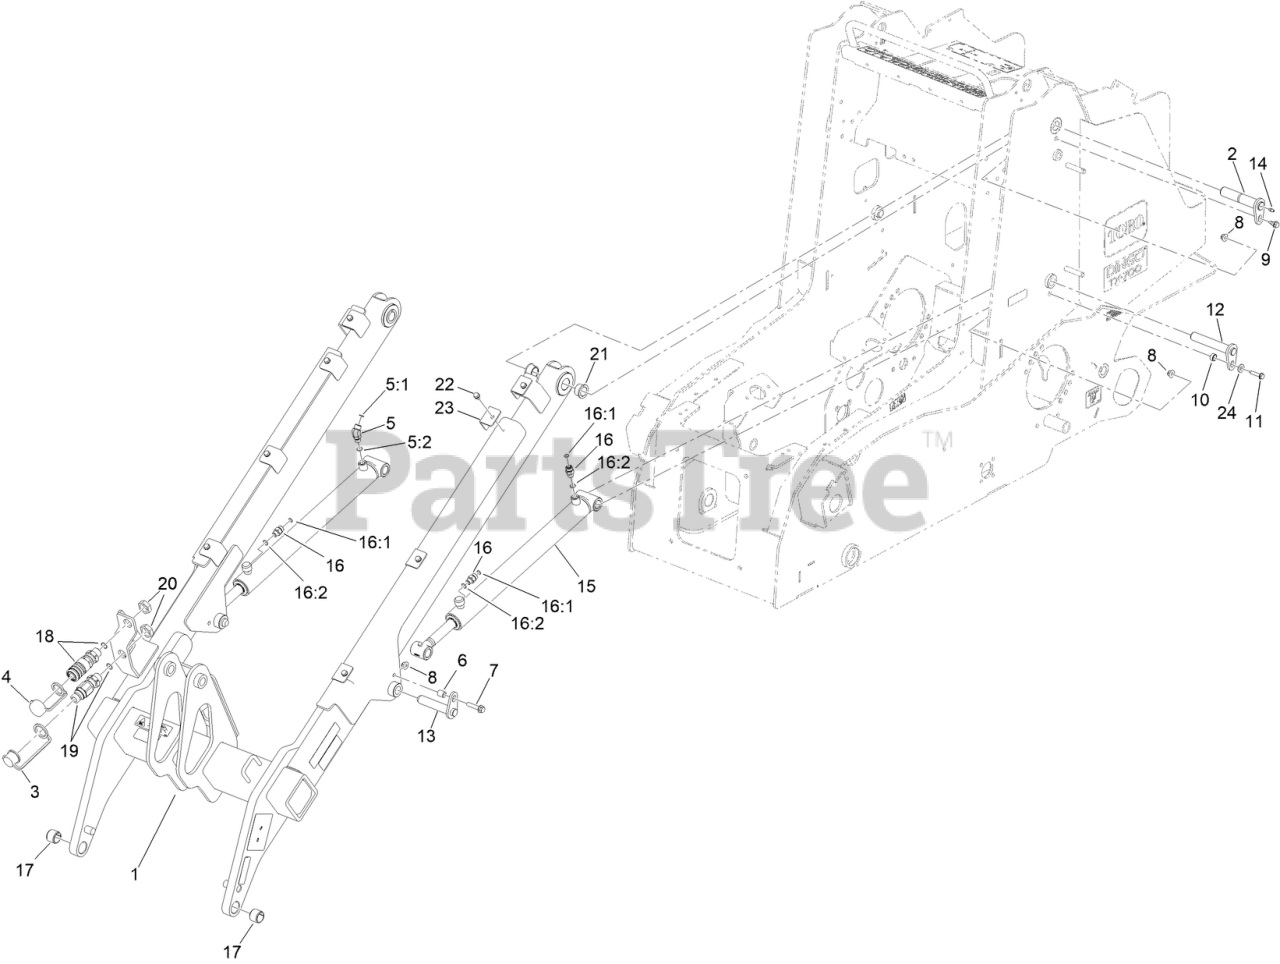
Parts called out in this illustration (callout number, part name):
1	LOADER ARM ASM
2	PIN-FLAG
3	CAP-DUST, NIPPLE
4	CAP-DUST, COUPLER
5	FITTING-ELBOW, 45 DEG
5:1	O-RING
5:2	O-RING
6	SPACER
7	SCREW-HHF
8	NUT-HF, NI
9	BOLT-SHOULDER
10	TUBE-SPACER
12	PIVOT PIN ASM (WELDED)
13	PIVOT PIN ASM (WELDED)
14	FITTING-GREASE
15	CLY-HYD
16	FITTING-STRAIGHT
16:1	O-RING
16:2	O-RING
17	BUSHING-TENSION
18	COUPLER ASM,BULKHEAD,
19	COUPLER ASM,BULKHEAD,
20	NUT-LOCK, BULKHEAD
21	BUSHING-FLANGE
22	SCREW-HWH
23	PLATE-RETAINER, HOSE
24	SPACER
